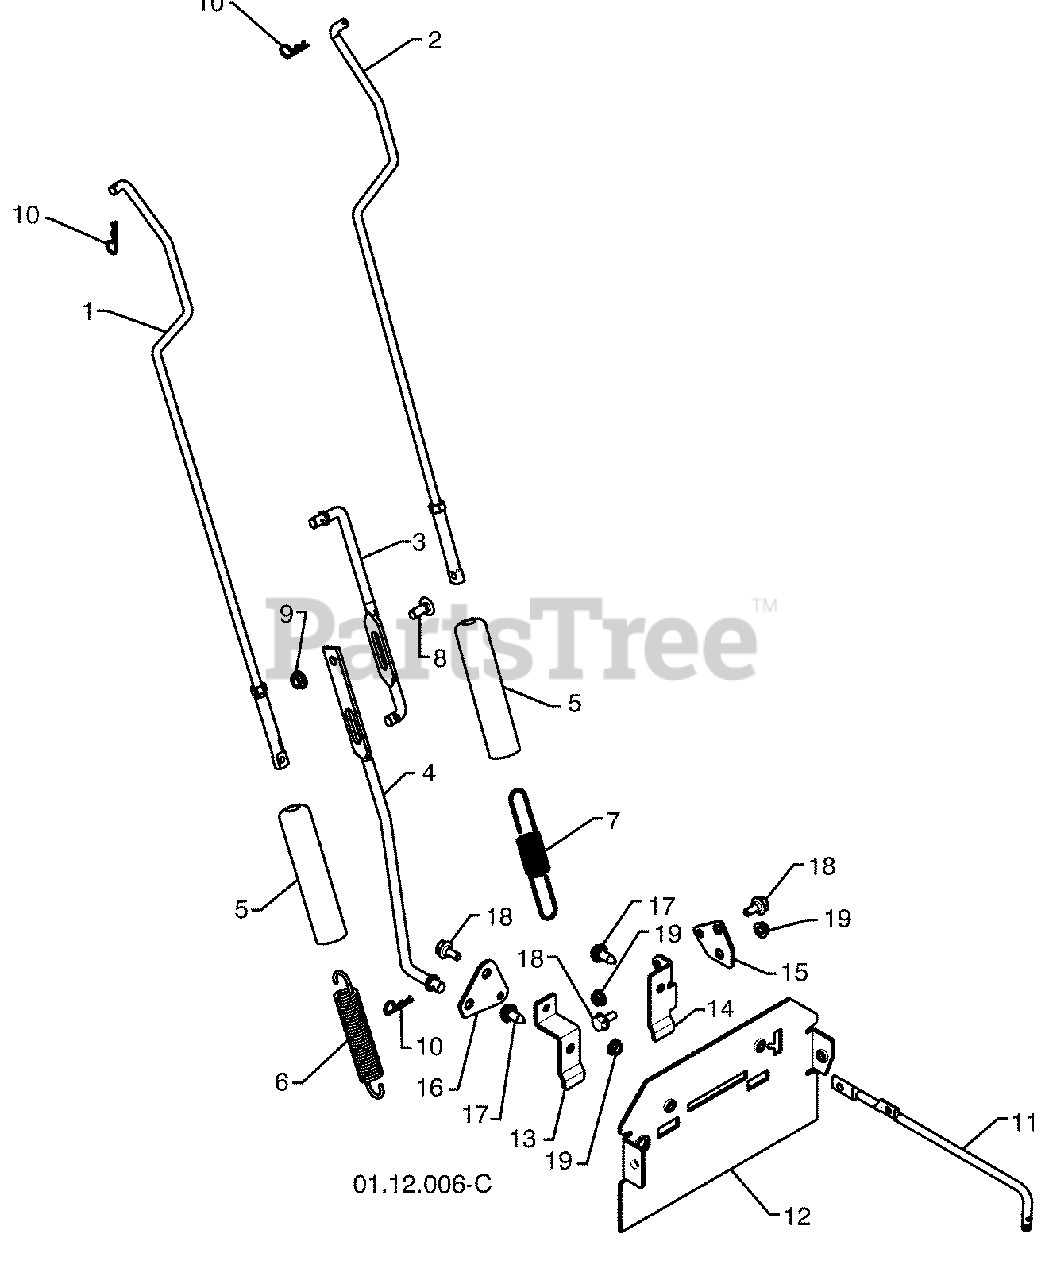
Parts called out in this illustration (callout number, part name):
1	IMPELLER ROD ASSEMBLY
2	TRACTION ROD ASSEMBLY
3	SHIFTER ROD TOP
4	SHIFTER ROD BOTTOM
5	SPRING SLEEVE
6	IMPELLER SPRING
7	TRACTION SPRING
8	CARRIAGE BOLT 5/16-18 X .750
9	NUT 5/16-18
11	CLUTCH ROD
12	REAR PLATE
13	SHIFTER PLATE BRACKET
14	CLUTCH PLATE BRACKET
15	CLUTCH PLATE
16	SHIFTER PLATE
17	BOLT 5/16-18 X .500
18	SHOULDER BOLT 1/4-20 X .500
19	NUT 1/4-20
